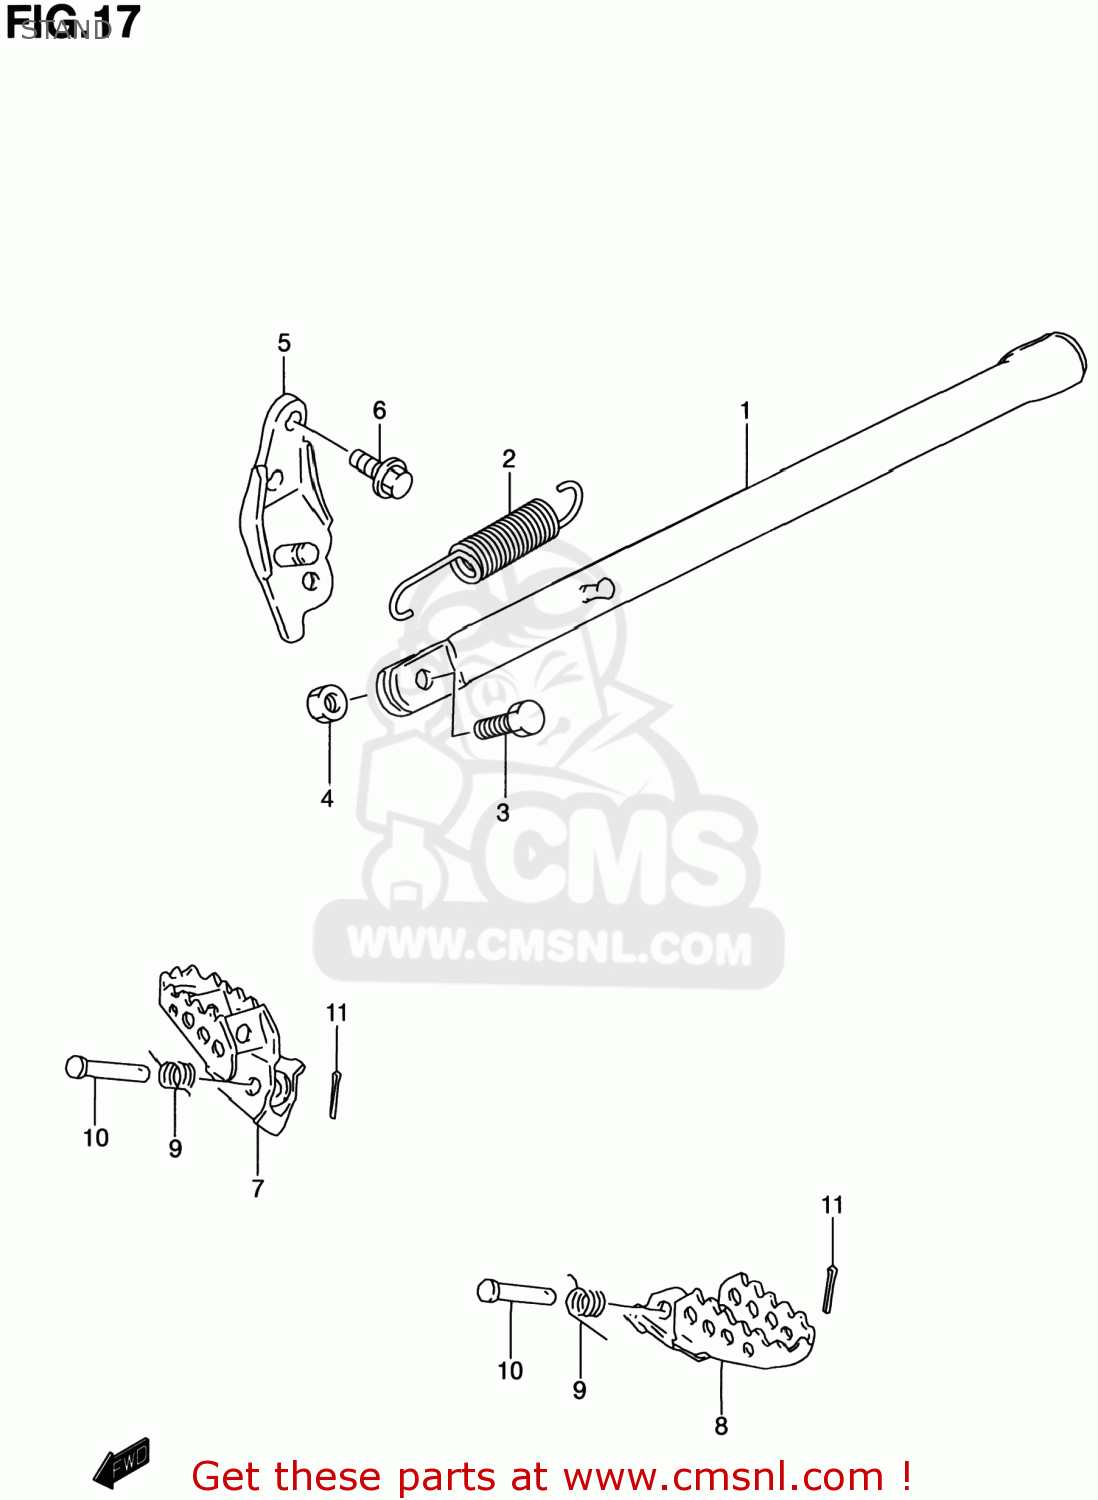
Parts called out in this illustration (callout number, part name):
1	STAND,PROP(BLACK)
2	SPRING
3	BOLT(8X25)
4	NUT
5	BRACKET,PROP STAND(BLACK)
6	BOLT
7	FOOTREST,FR,R
8	FOOTREST,FR,L
9	SPRING
10	PIN
11	PIN
